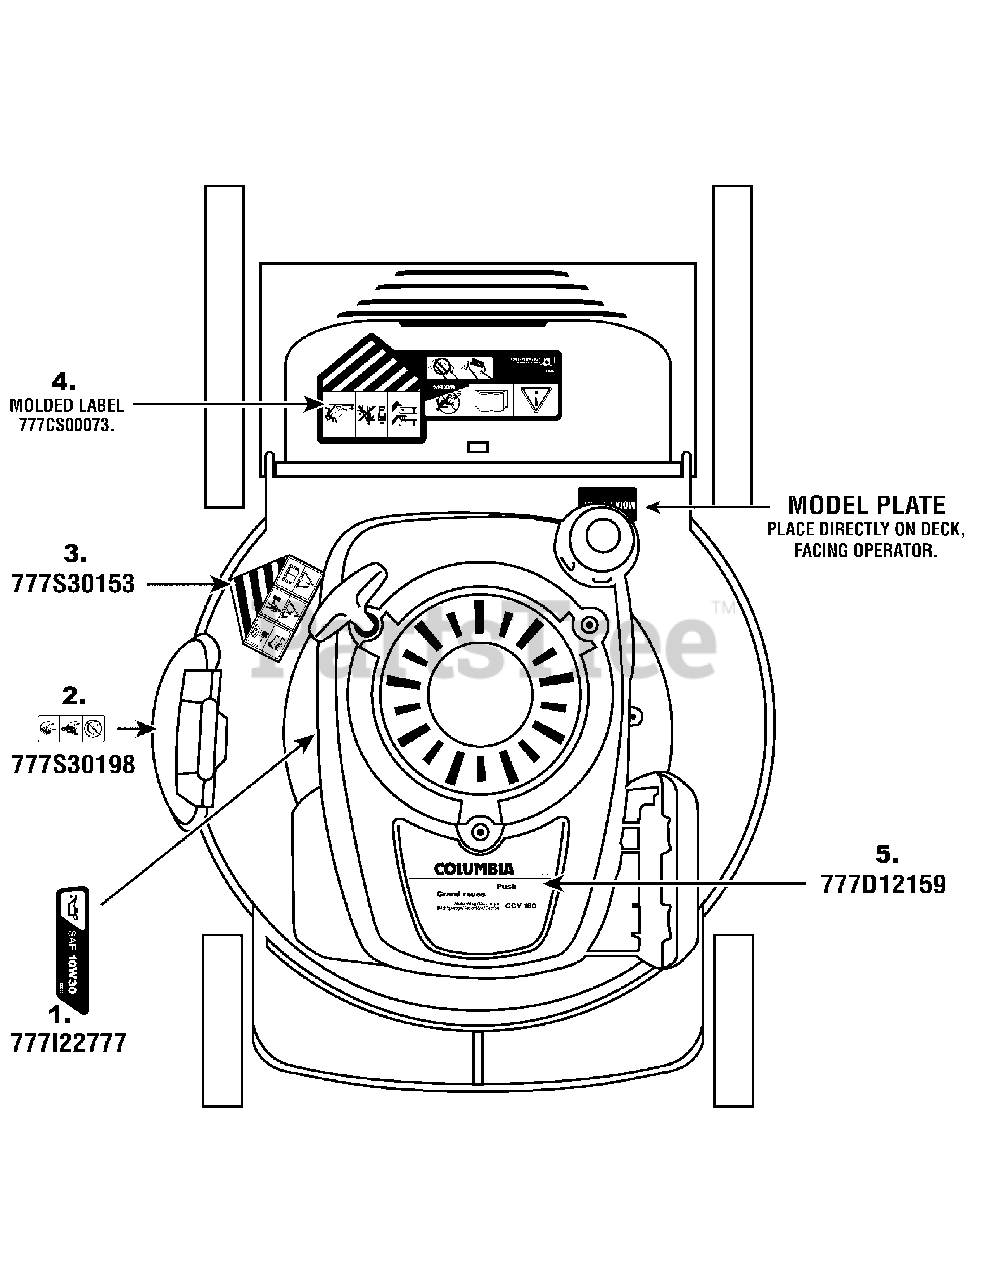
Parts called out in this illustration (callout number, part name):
3	LABEL-DANGER CHUTE
4	LABEL
5	LABEL-ENG SHROUD COLUMBIA
